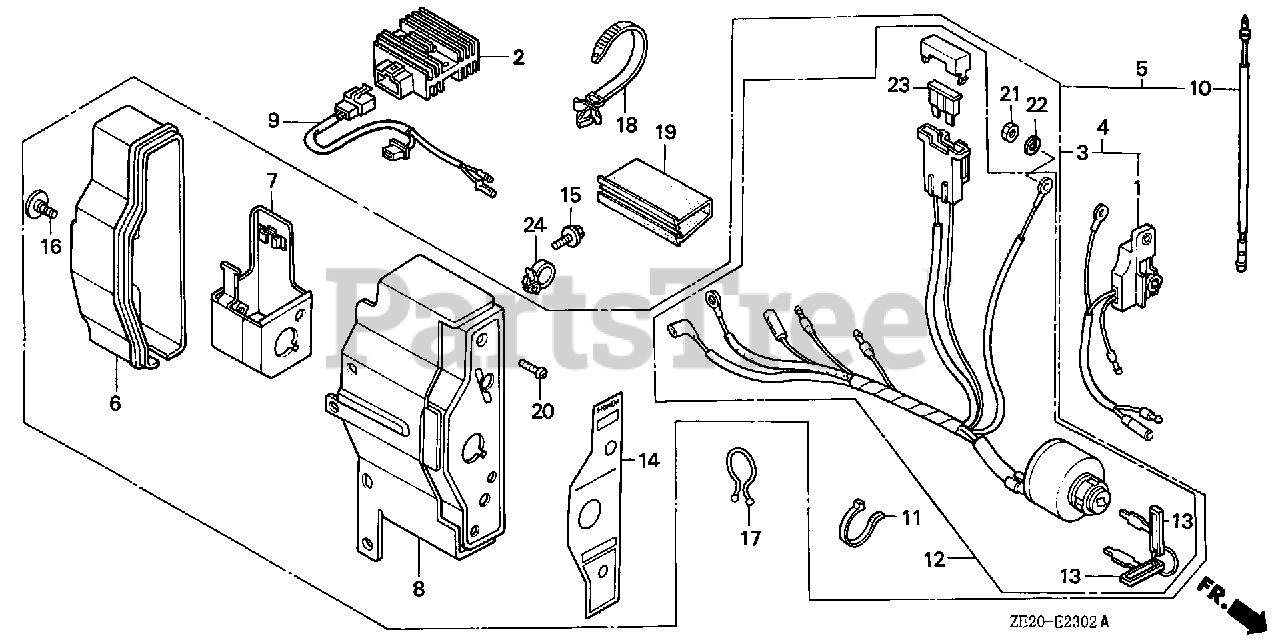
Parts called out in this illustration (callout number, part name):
1	ALERT UNIT, OIL (SEL)
2	RECTIFIER ASSY., REGULATOR (10A)
4	BOX ASSY., CONTROL (10A) *R8* (EXP-ALERT) (BRIGHT RED) (NOT AVAILABLE)
6	CASE, CONTROL
7	BRACKET, CASE MOUNTING
8	PANEL, CONTROL *R280* (POWER RED)
9	SUB-WIRE HARNESS ASSY.
11	BAND
12	SWITCH ASSY., COMBINATION (10A-CHARGE)
13	KEY
14	MARK, CONTROL BOX (EXTERNAL-ALERT)(REGULATOR) (NOT AVAILABLE)
15	BOLT, FLANGE (6X12) (CT200)
16	SCREW, SPECIAL (6X12)
17	CLIP, PURSE LOCK
18	STRAP, CABLE (118MM) (BLACK)
19	TUBE, FASTENER (30MM)
20	SCREW, PAN (4X12)
21	NUT, HEX. (4MM)
22	WASHER, SPRING (4MM)
23	FUSE, BLADE (15A)
24	HOLDER, STOP SWITCH WIRE
